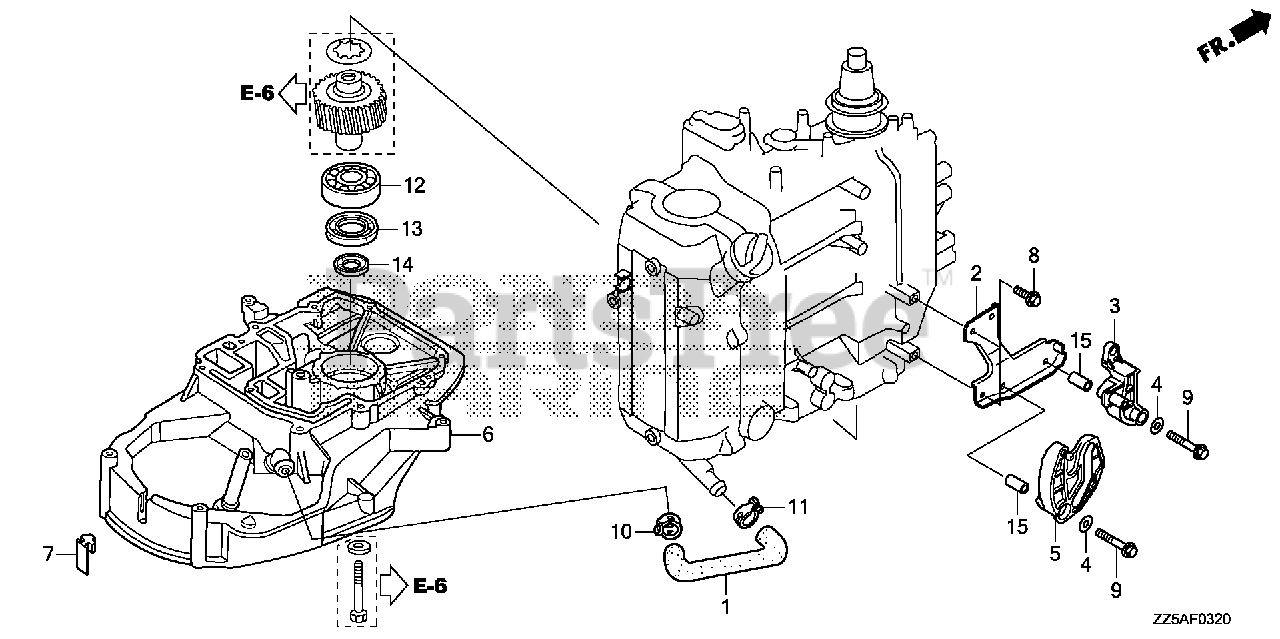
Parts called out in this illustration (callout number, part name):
2	BRACKET, THROTTLE ARM
3	ARM, THROTTLE
4	WASHER, PIVOT
5	CAM, THROTTLE
6	CASE, PRIMARY GEAR *NH8* (DARK GRAY)
7	RUBBER, MOUNT CASE SEAL
8	BOLT, FLANGE (6X14) (CT200)
9	BOLT, FLANGE (6X30)
10	CLAMP, TUBE (D18.8)
11	CLAMP, TUBE (D21)
12	BEARING, RADIAL BALL (6205)
13	OIL SEAL (25X40X7)
14	SEAL, WATER (17X26X7)
15	COLLAR, DISTANCE (6X11X20.6)
